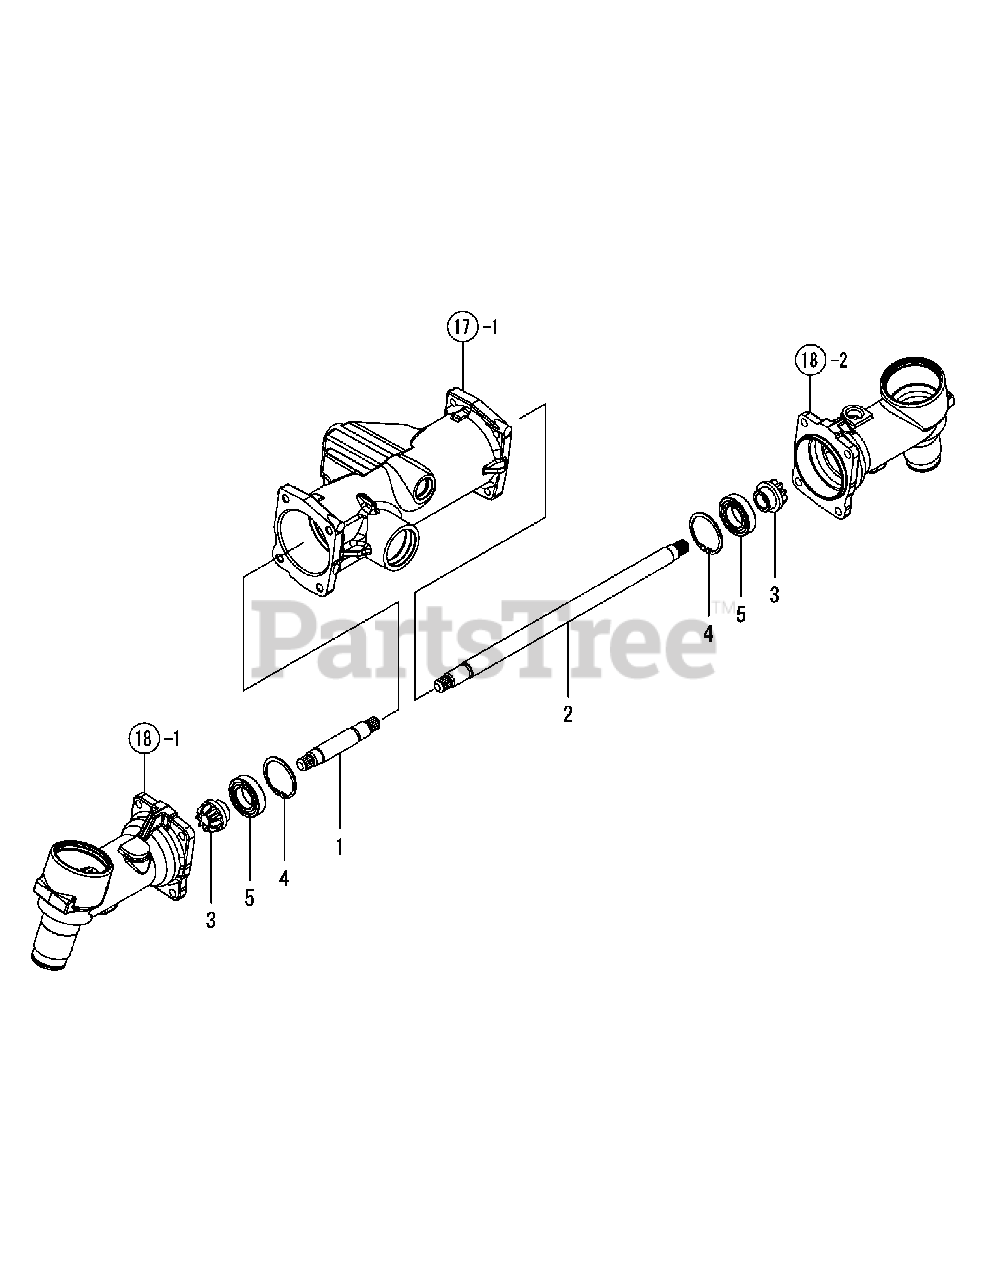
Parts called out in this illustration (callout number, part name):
1	SHAFT L, FRONT 1
2	SHAFT R, FRONT 1
3	GEAR 9T, BEVEL
